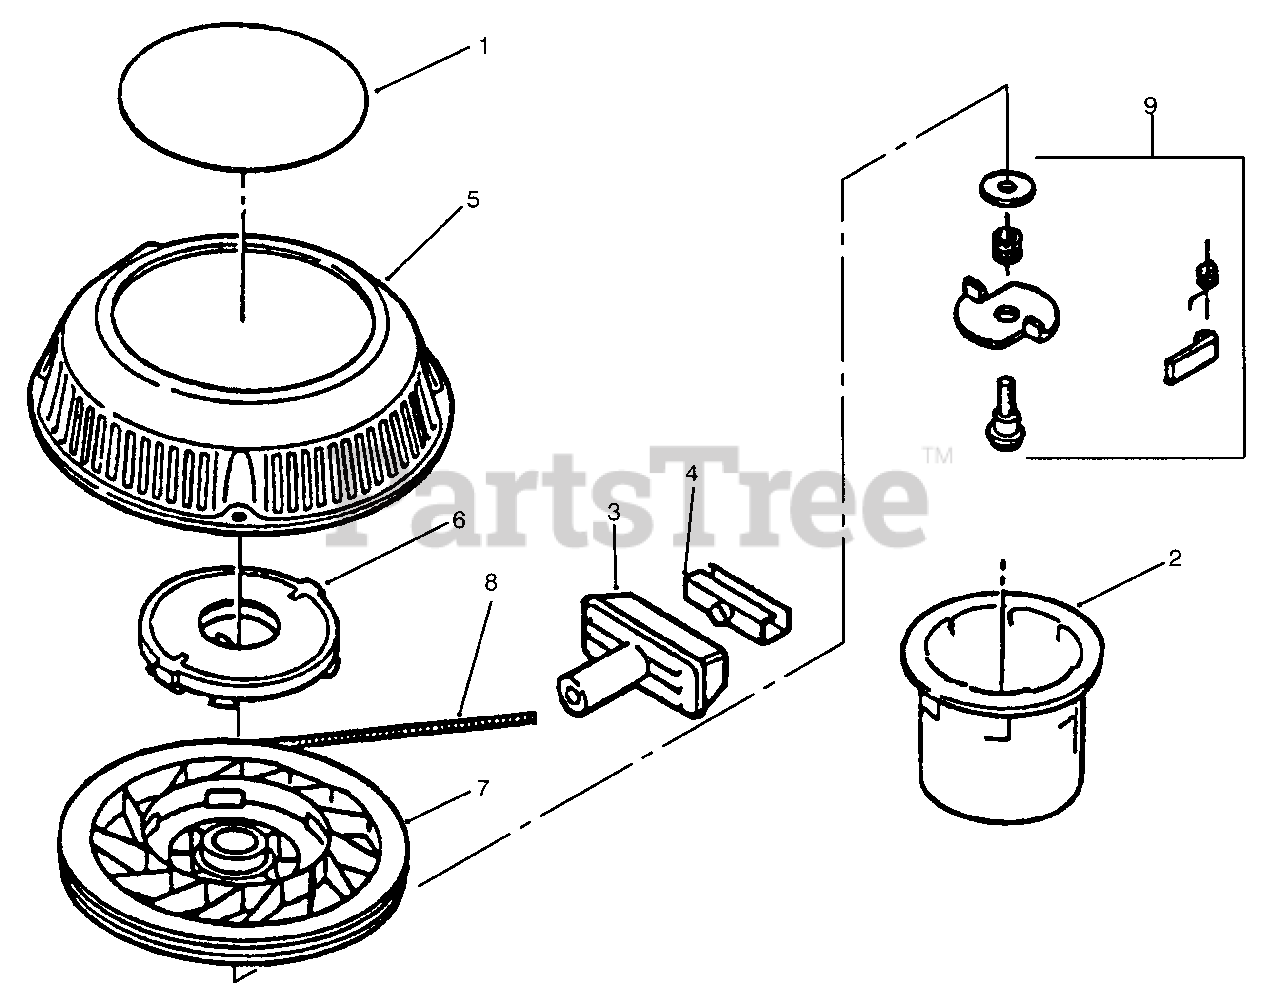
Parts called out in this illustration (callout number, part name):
1	Decal
2	Hub-Starter
3	Handle-Starter
4	Insert-Clip, Rope
5	Housing-Starter
6	Recoil Spring & Keeper
8	Rope
9	Assembly-Dog Kit
